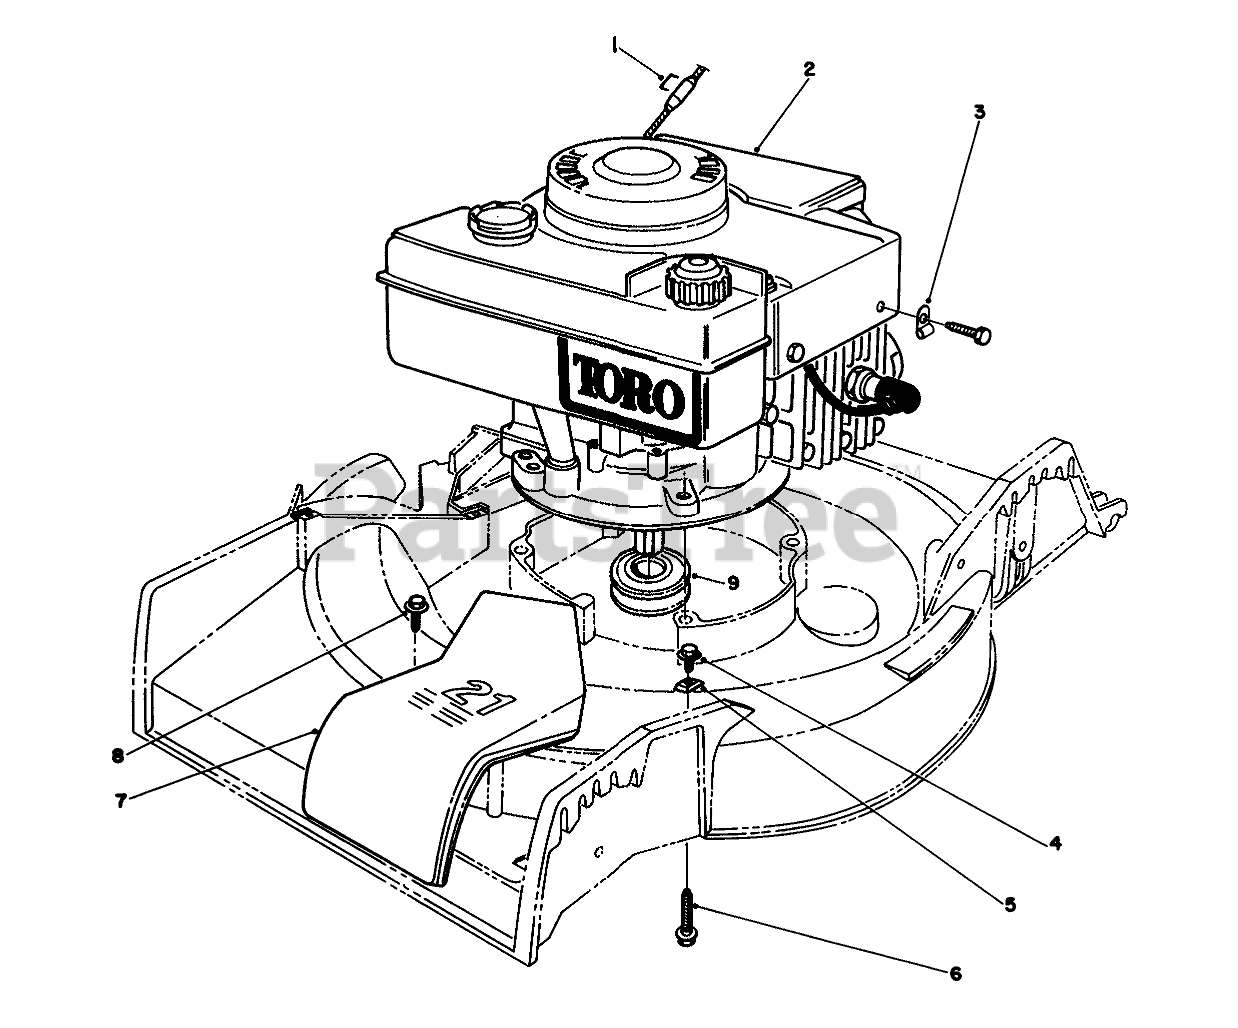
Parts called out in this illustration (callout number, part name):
1	Staple
3	CLAMP
4	SCREW-HWHTF
5	Cable Clamp
6	3/8-16 X 2-3/4 CAPSCR
7	BELT COVER 21" S D
8	SCREW
9	PULLEY-DRIVER
